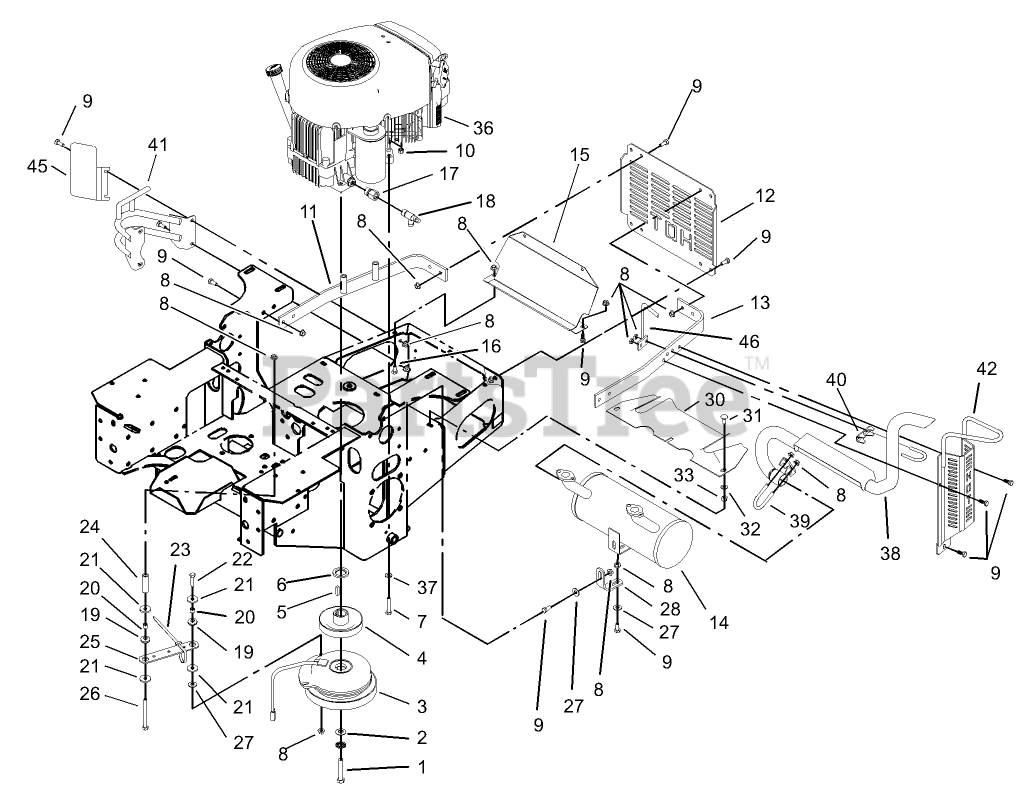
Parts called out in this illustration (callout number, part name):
1	SCREW-HH
2	WASHER-SPRING
3	CLUTCH
4	PULLEY
6	Spacer-Crankshaft
7	SCREW-HH
8	NUT-HF
9	SCREW-HH
10	NUT-LOCK, NI
11	STRAP-GUARD, ENGINE
12	SHIELD-ENGINE
13	STRAP-GUARD, LH
14	Muffler
15	Shield-Heat
16	SCREW-HH
17	Adapter
18	Valve-Drain, Oil
19	GROMMET
20	SPACER
21	WASHER
22	SCREW-HH
23	TIE-PLASTIC
24	Spacer
25	STRAP-CLUTCH, BRAKE
26	SCREW-HH
27	WASHER-FLAT
28	BRACKET-SUPPORT, MUFFLER
30	SHIELD-HEAT
31	BOLT-CARR
32	WASHER-PLAIN
33	NUT-LOCK, NI
37	WASHER-SPRING
38	TAILPIPE
41	RH Exhaust Guard ASM
42	LH EXHAUST GUARD ASM
45	RH EXHAUST GUARD ASM
46	LH REAR GUARD ASM
